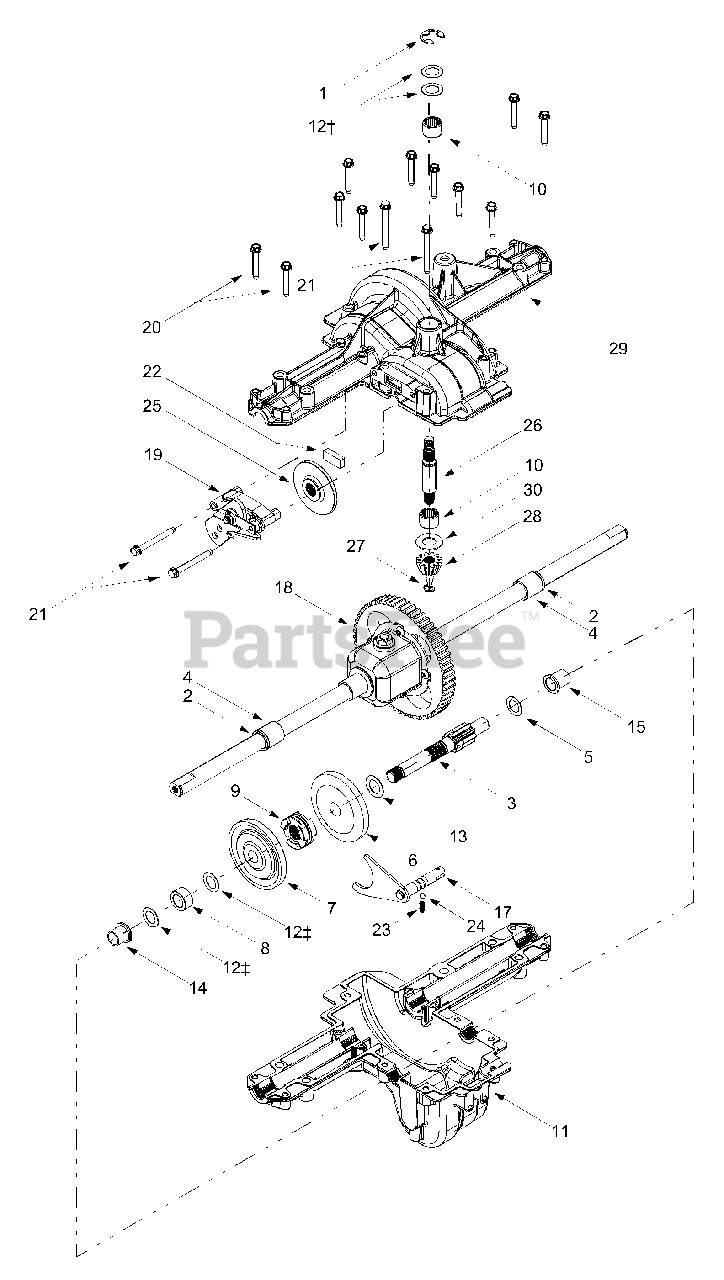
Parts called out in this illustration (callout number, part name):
1	E-ring, .75
2	Seal, .75 x 1.0 x .125
3	Drive Shaft
4	Sleeve Bearing, .75 x .1.0 x 1.0
5	Thrust Washer, 1.0 x .632 x .0
6	42-tooth Bevel Gear
7	42-tooth Bevel Gear
8	Spacer, .633 x 1.0 x .513
9	Clutch Collar
10	Needle Bearing, .625 x .813 x .495
11	Lower Housing
12	Flat Washer, 5/8 x 1.0 x .030
13	Flat Washer, .70 x 1.125 x .031
14	Flange Bearing, 5/8 x 3/4 x 3/4
15	Flange Bearing, 5/8 x 3/4 x 15/16
17	Detent Shaft Assembly
18	Differential Assembly
19	Brake Assembly
20	Self-tapping Screw, 1/4-20 x 1.625
21	Self-tapping Screw, 1/4-20 x 2.375
22	Brake Pad
23	Compression Spring
24	Detent Ball
25	Brake Disc
26	Input Shaft
27	Retaining Ring, .437
28	14-tooth Bevel Pinion
29	Upper Housing
30	Thrust Washer, .635 x 1.25 x .042
